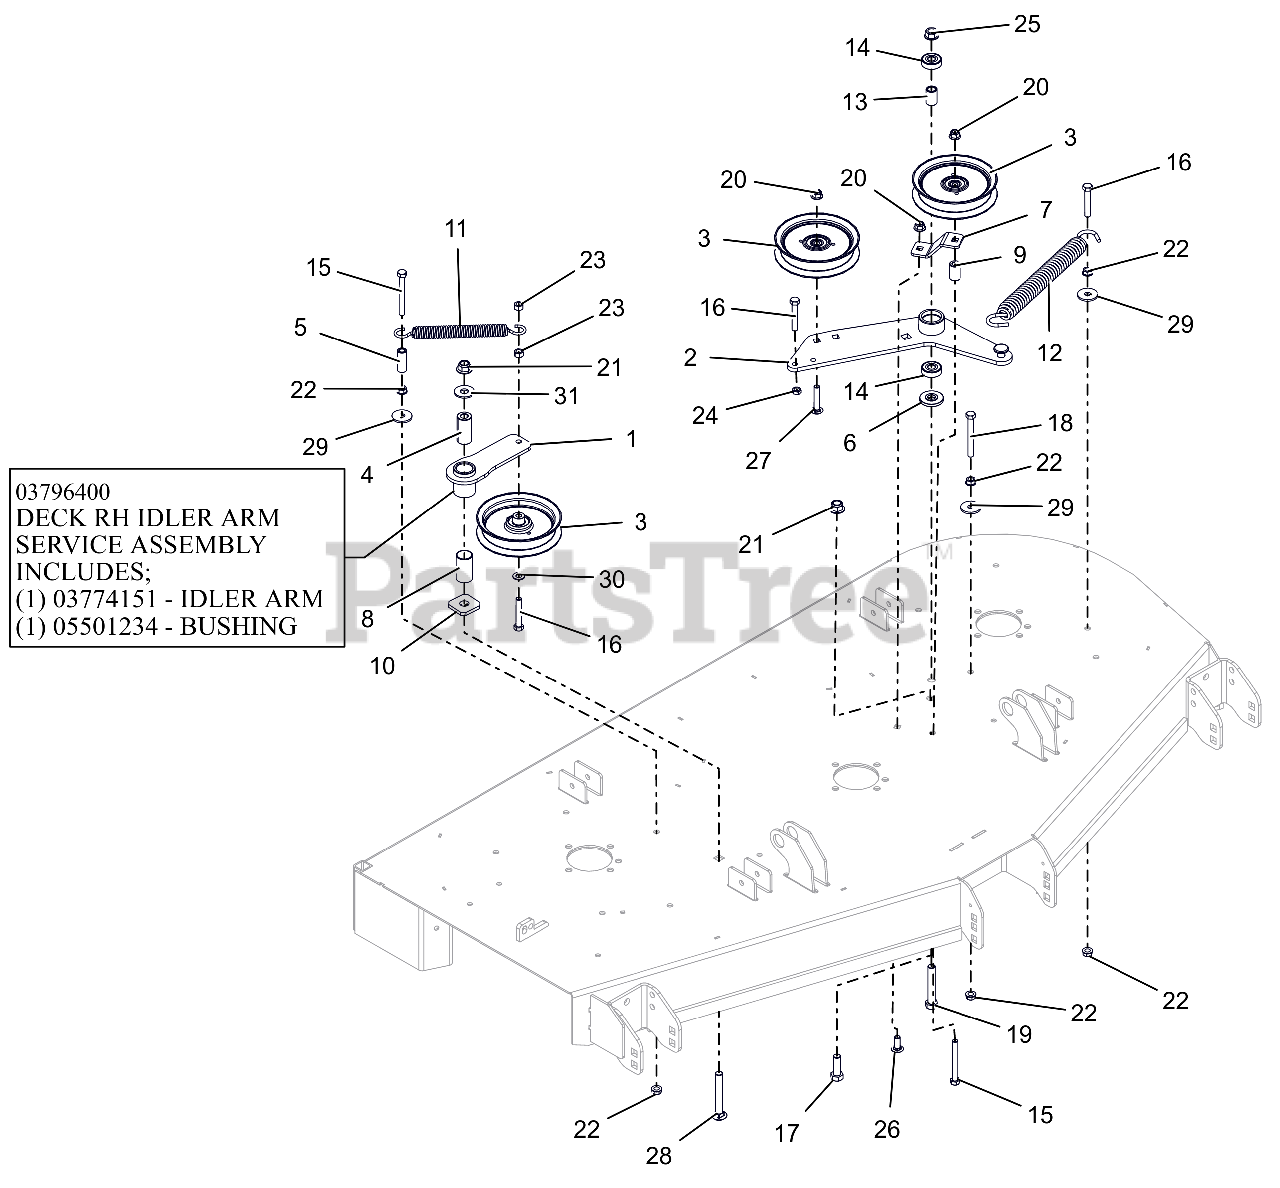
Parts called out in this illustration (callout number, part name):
1	WMT, IDLER ARM - BLACK
1	ASM, IDLER ARM (DECK)
2	DECK PTO IDLER ARM WLDMT - BLK
3	IDLER, FLAT 5.00"
4	BSHG, SPCR .502X.997X2.03 PM
5	SPACER, .375IDX.625ODX1.66 PM
6	SPACER, IDLER ARM
7	PTO FIXED IDLER MTG BRKT -RED
8	BSHG, 1.00X1.125X1.937
9	BUSHING, SLV .380X.750X1.190
10	WSHR-FLT .640X1.75X.250
11	SPRING, EXTENSION
12	SPRING, EXTENSION
13	SPACER .510 X .75 X 1.1485
14	BRG-BALL .500X1.38X.437
15	BLT, HEX .38-16X3.25 G5 ZCC
16	BLT,HEX .38-16X2.25 G5 ZCC
17	BLT,HEX .50-13X1.50 G5 ZCC
18	BLT, HEX .38-16X3.25 G5 ZCC
19	BLT, HEX .50-13X3.00 G5 ZCC
20	NUT,NYL-FLG .38-16 GF ZCC
21	NUT,NYL-FLG .50-13 GF ZCC
22	NUT, SPNLK-FLG .38-16 G5 ZCC
23	NUT-LK-CTR .38-16 ZC120
24	NUT-JAM .375-16 G2 ZCC
25	NUT-LK-CTR-FLG .500-13 GG ZCC
26	BLT,RHSSN .38-16X1.00 G5 ZCC
27	BLT,RHSSN.375-16X2.00 G5 ZCC
28	BLT, RHSN .50-13X3.50 G5 ZCC
29	WSHR,FLT .406X1.375X.135 ZCC
30	WSHR,FLT .406X.812X.065 ZCC
31	WSHR,FLT .563X1.375X.109 ZCC
